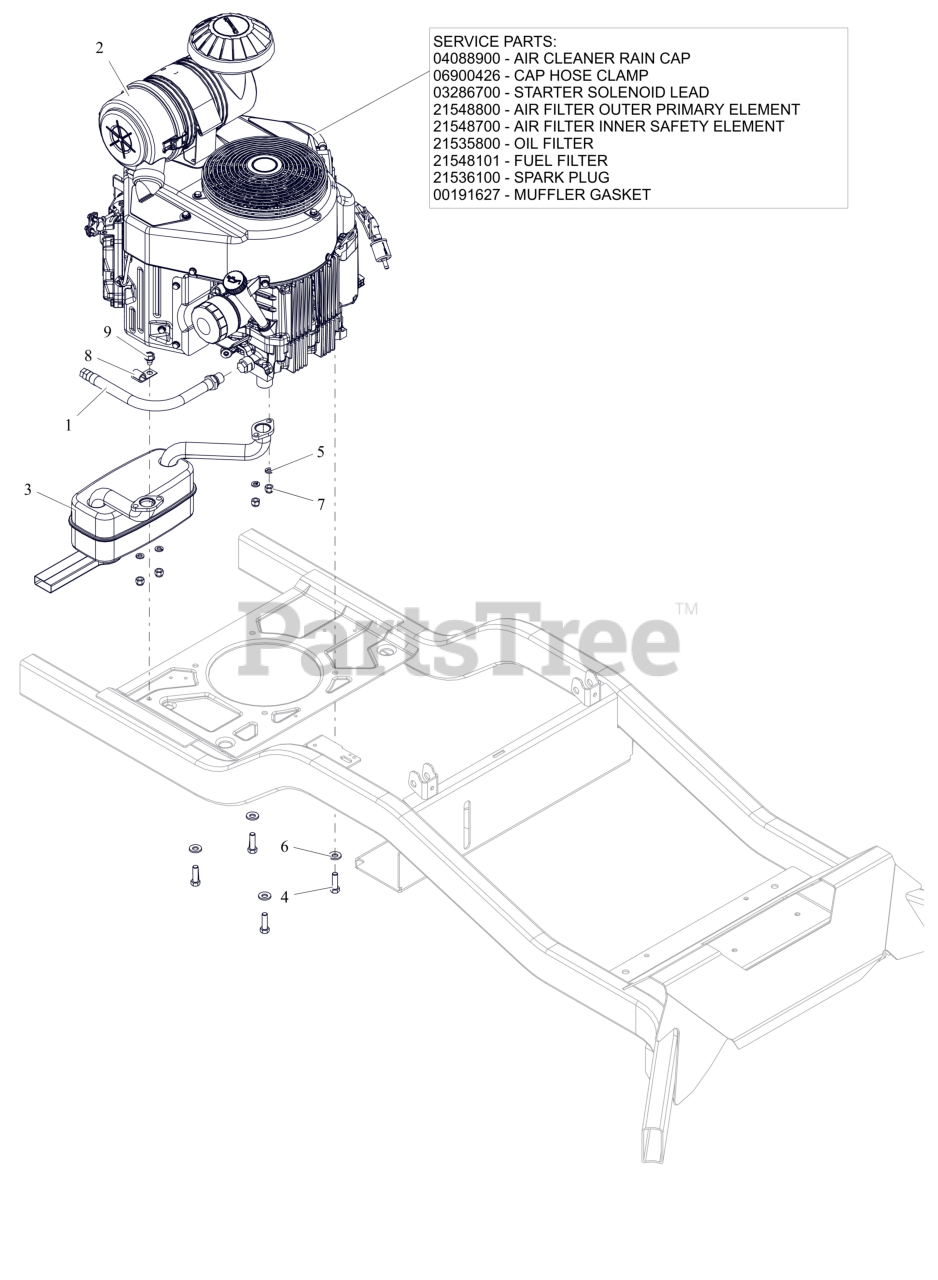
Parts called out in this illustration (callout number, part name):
1	HOSE, OIL DRAIN
2	ENGINE, KAWASAKI - FX730
2	CAP, KAW 11065-7025
2	CLAMP, HOSE #36 SS 1.813-2.75
2	LEAD - STARTER SOLENOID
2	FILTER, OUTER
2	FILTER,OIL - KAW
2	FUEL FILTER-KAWASAKI FR
2	PLUG, SPARK
2	GASKET, MUFFLER S/O
3	MUFFLER, KAWASAKI
4	BLT, HEX .38-16X1.25 G5 ZCC NT
5	WSHR,LK-REG .312X.078 ZCC
6	WASHER, 3/8" SPRING DISC
7	NUT, LK-CTR-JAM M8-1.25 GR8.8 ZC120
8	J-CLAMP
9	SCR,TAP .375-16X.50 HWH TR ZCC
